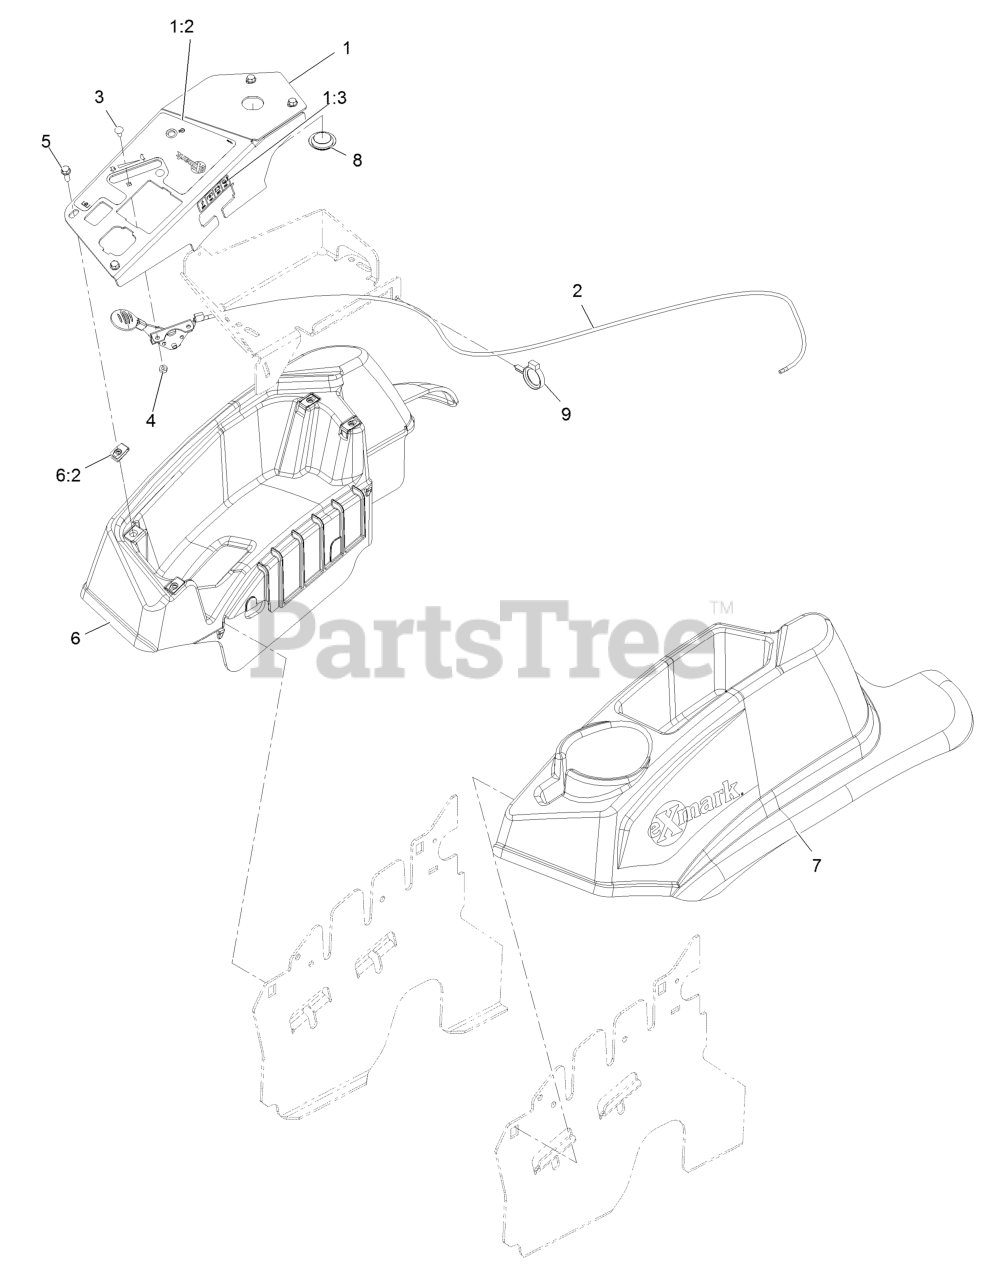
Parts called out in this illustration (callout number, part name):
1	ASM,CONTROL PANEL W/DECAL
1:2	DECAL-CONTROL PANEL EFI
1:3	DECAL-FUSES
2	ASM,THROTTLE CABLE
3	BOLT-CARR
4	NUT-LOCK, NI
5	SCREW-HWH
6	CONSOLE,RH AS ASM
6:2	Nut-Retainer-Panel 1/4-20
7	CONSOLE, LH AS
8	PLUG-PLASTIC
9	CLAMP-HOSE
